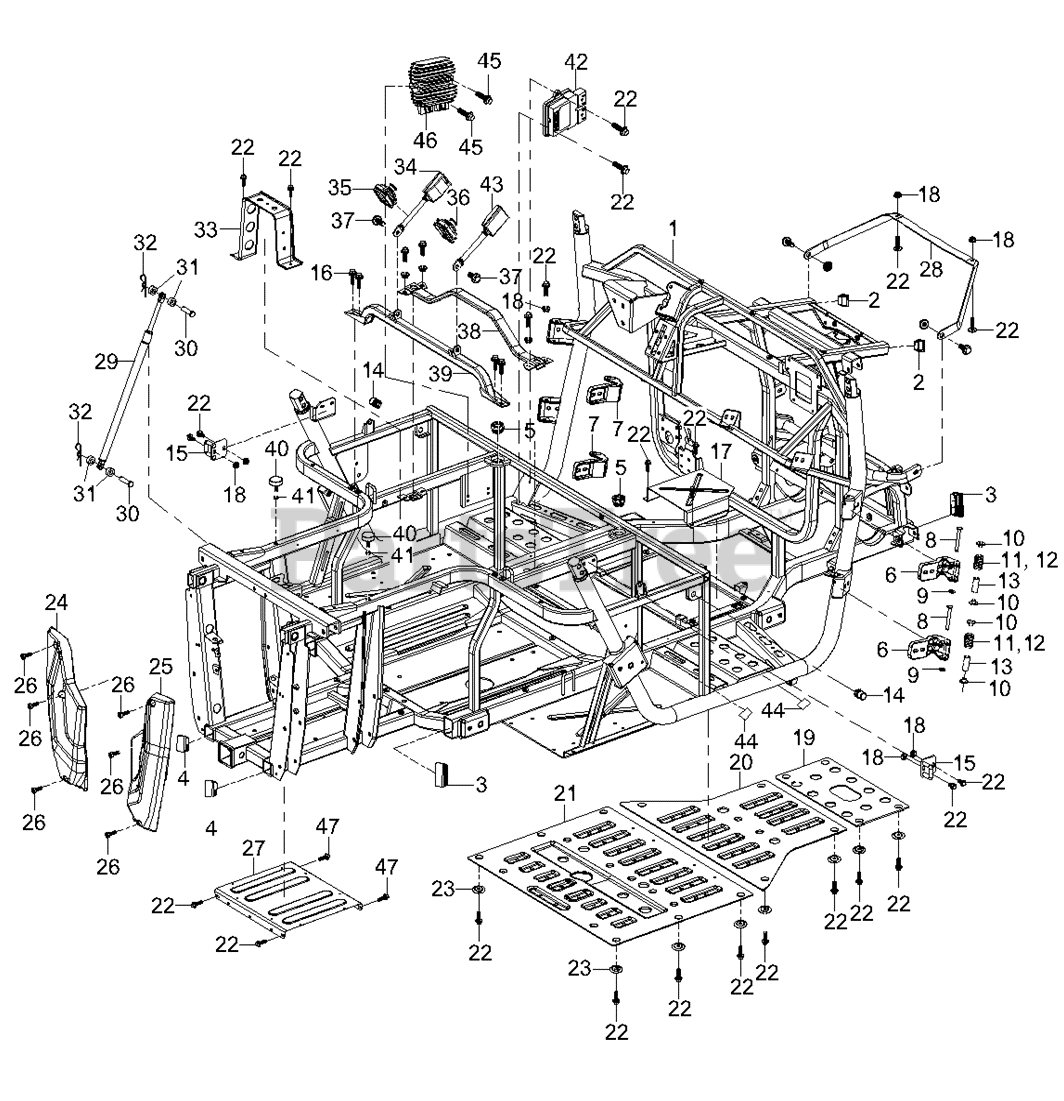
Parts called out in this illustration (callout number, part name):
1	FRAME
2	PLASTIC CAP 30X30
3	RUBBER BLOCK
4	PLASTIC CAP 40X40
5	RUBBER WASHER
6	DOOR HINGE
7	DOOR HINGE
8	SHOULDER PIN 8X70.5
10	PLASTIC BUSHING
11	TORSION SPRING
12	TORSION SPRING
14	DOOR DAMPER I
15	DOOR HOOK KIT
16	HEXAGON FLANGE BOLT M8X20
17	PEDAL PLATE
18	HEX FLANG NUT M6
19	FRONT SKID PLATE
20	MIDDLE SKID PLATE
21	REAR SKID PLATE
22	HEXAGON FLANGE BOLT M6X16
23	CAP WASHER
24	REAR BUMPER I
25	REAR BUMPER II
26	SOCKET HEX FLAT HEAD BOLT M6X16
27	DIFF HEAT SHIELD (REAR)
28	HOOD STRAP
29	GAS SPRING ASSEMBLY - CARGO BED
30	SHOULDER PIN 12X47
31	RUBBER WASHER 13 x 10
32	SPRING PIN
33	BATTERY BOX STRAP
34	SEAT BELT BUCKLE
35	SEAT BELT BUCKLE CAP LH
36	SEAT BELT BUCKLE CAP RH
37	HEX FLANGE BOLT M10X1.25X20
38	SEAT STIFFENER SHELF KIT
39	SEAT BELT MOUNITING BRACKET
40	SPIRAL CUSHION GASKET
41	NUT HEXAGON FLANGE HEAD M8
42	ECU CONTROLLER (550) (MY18+)
42	ECU CONTROLLER (750) (MY18+)
43	PASSENGER SIDE SEAT BELT
44	BATTERY CUSHION
45	HEXAGON FLANGE BOLT M6X35
47	HEXAGON FLANGE BOLT M6X25
